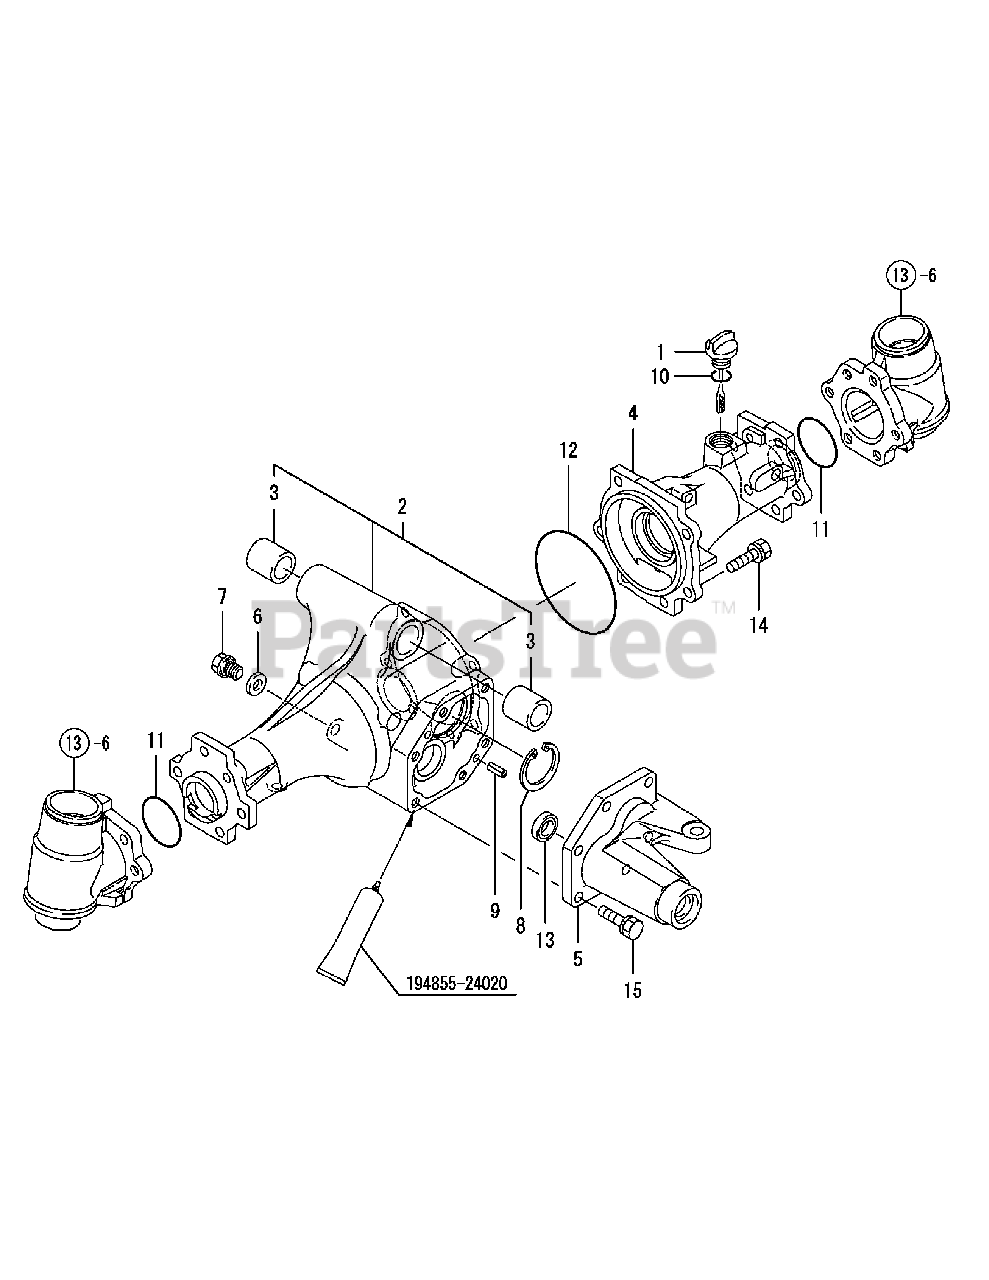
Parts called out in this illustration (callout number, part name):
1	Cap W/Dipstick
2	Case L Comp, F. Axle
4	Case R,Front Axle
5	Cover,Front Axle Cas
6	Gasket(20*12*2
7	Bolt M 12X 12 Plated
9	Spring Pin 8X20
10	O-Ring 1A P-18.0
11	O-Ring 1A G-50.0
12	O-Ring 1A G-115.0
13	Seal Tc17 30 07, Oil
